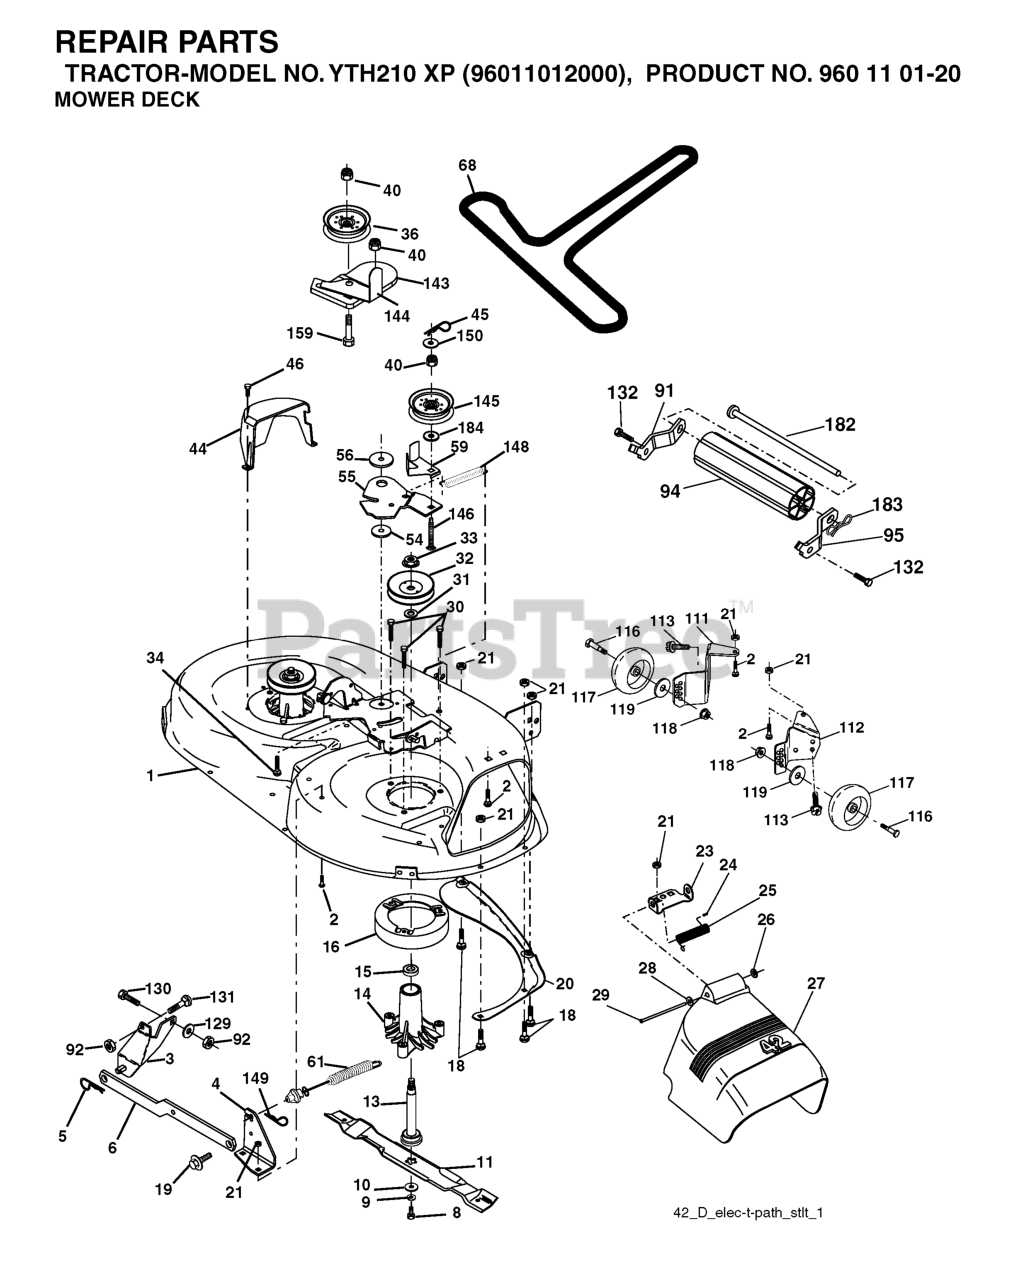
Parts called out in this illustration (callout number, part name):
1	42" DECK KIT
2	RP BOLT 5/16-18 X3/4 ZN/YEL GR
3	BRKT ASM SWAY BAR
4	BRACKET SWAY BAR 42" DECK
5	RETAINER-SPRNG RB
6	BAR SWAY DECK
8	BLADE BOLT
9	LOCKWASHER
10	WASHER.BLADE
11	42" HI-LIFT BLADE
13	SHAFT ASM VENT
14	HOUSING.MANDREL.VENTED (MACHD)
16	STRIPPER.MANDREL.ROUND.BLACK
18	BOLT
19	BOLT SHD 5/16-18
20	BAFFLE.VORTEX
21	LOCKNUT
23	BRKT, DEFL. MOWER
24	CAP-SLEEVE LT
25	SPRING TORSION
26	NUT PUSH M
27	SHIELD DEFLECTOR
28	Washer 11/32 x 5/8 x 16 Ga SD
29	ROD.HINGE
30	SCREW, WASHER HEAD
31	WASHER.SPACER.MANDREL
32	PULLEY/MANDREL
33	NUT.FLANGE.LOCK.TOP
34	BOLT.3/8-16X1.50
36	FLAT IDLER PULLEY
40	NUT LOCK FLG 3/8-16 UNC
44	GUARD MANDREL LH BLACK
45	RETAINER M
46	SCREW.1/4-20X5/8
55	ARM IDLER 42" MOWER LT/YT
56	SPACER.RETAINER.MOWER
59	GUARD, BELT
61	SPRING EXT ELEC CLUTCH
91	BRACKET ASM NOSEROLLER LH
92	NUT
94	NOSE ROLLER
95	BRACKET ASM NOSEROLLER RH
111	BRACKET, WHEEL
112	BRACKET, WHEEL
113	BOLT.5/16HEX.WHS.HD
116	BOLT M
117	WHEEL.GAGE.HALF.SPOKED
118	LOCKNUT
119	WASHER.5/16.FLAT.STE.STD.
129	WASHER
131	BOLT D
132	SCREW, 3/8-16X3/4
143	BRACKET, ARM IDLER
144	DNO KEEPER.BELT.42".CLUTCH.CBL
145	PULLEY
146	BOLT, CARRIAGE IDLER BLACK
148	IDLER RETURN SPRING
149	SPRING.RETAINER.YELLOW.ZINC
182	ROD ROLLER NOSE STANDARD
183	PIN.COTTER.7/16.BOW TI.
184	WASHER
